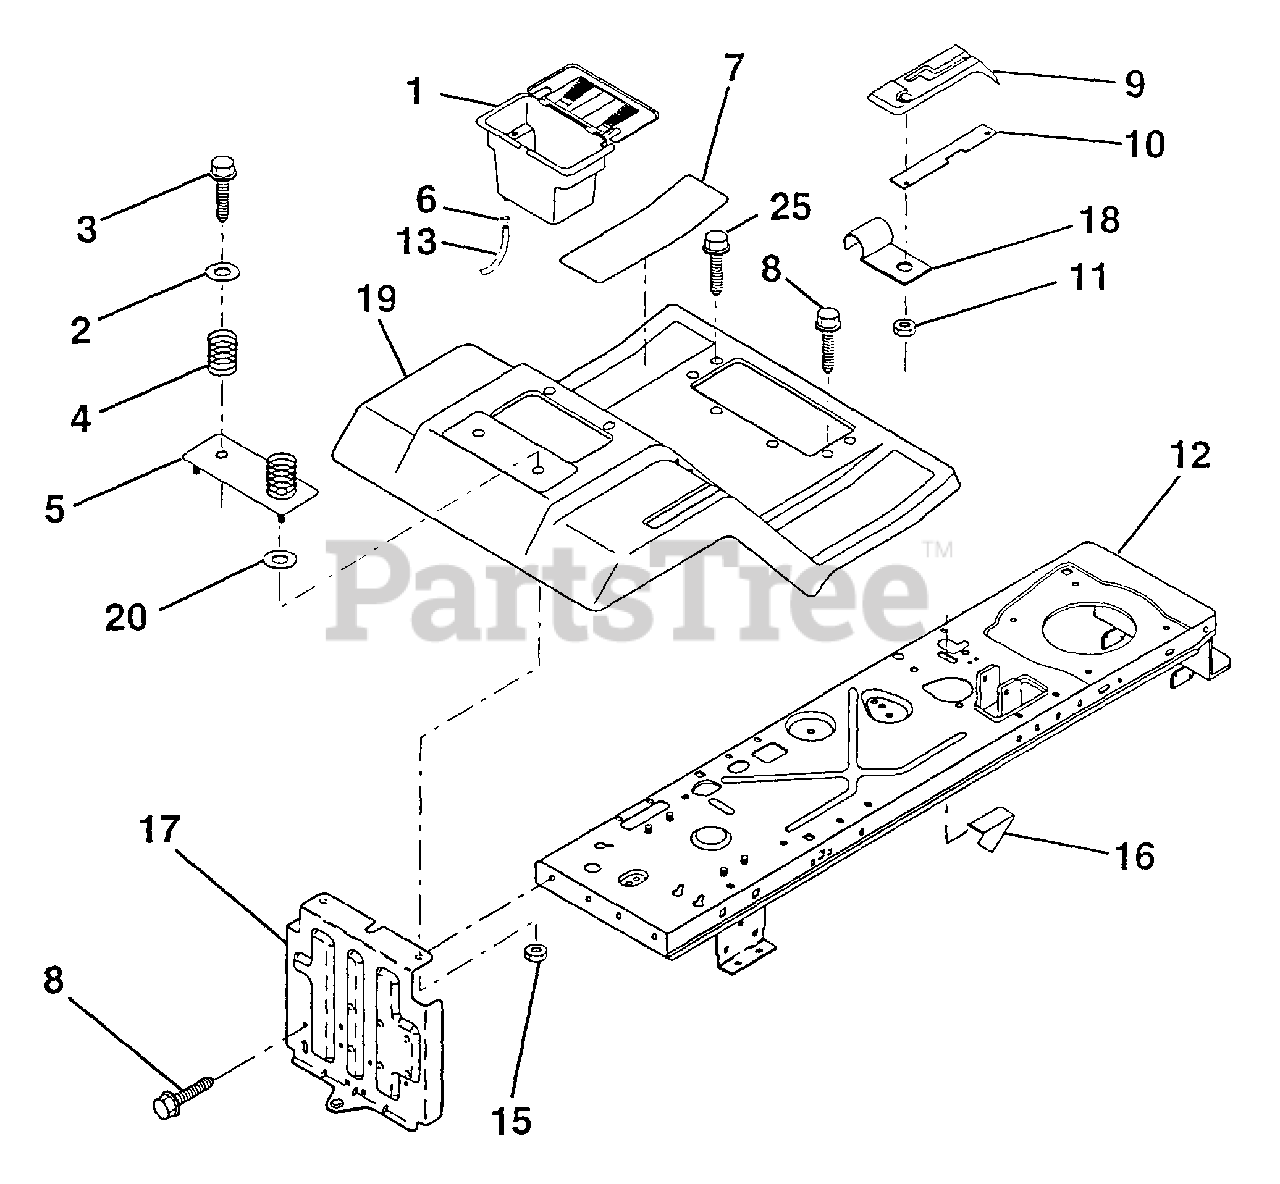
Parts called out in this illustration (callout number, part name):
1	Case, Battery
2	Washer 13/32 x 1-1/4 x 12 Ga.
3	Screw, Hex Wsh. Thrdrol. 3/8-16 x 3/4
4	Spring, Compression, Seat
5	Plate, Asm. Battery
6	Clamp, Hose
7	Pad, Footrest
8	Screw, Hex Wsh Thdrol. 5/16-18 x 3/4
9	Console, Shift Control
10	Bar, Shift Lock
11	Nut, Self-Thrd., Wsh. Head 3/16
12	Chassis Asm. Weldment
13	Tube, Battery Drain
15	Nut, Keps Hex 1/4-20 UNC
16	Switch Actuator (AYP part number)
17	Drawbar
18	Clip, Insulated
19	Fender/Footrest (AYP part number)
20	Washer 9/32 x 7/8 x 13 Ga.
25	Screw Hex 5/16-18 x 1
